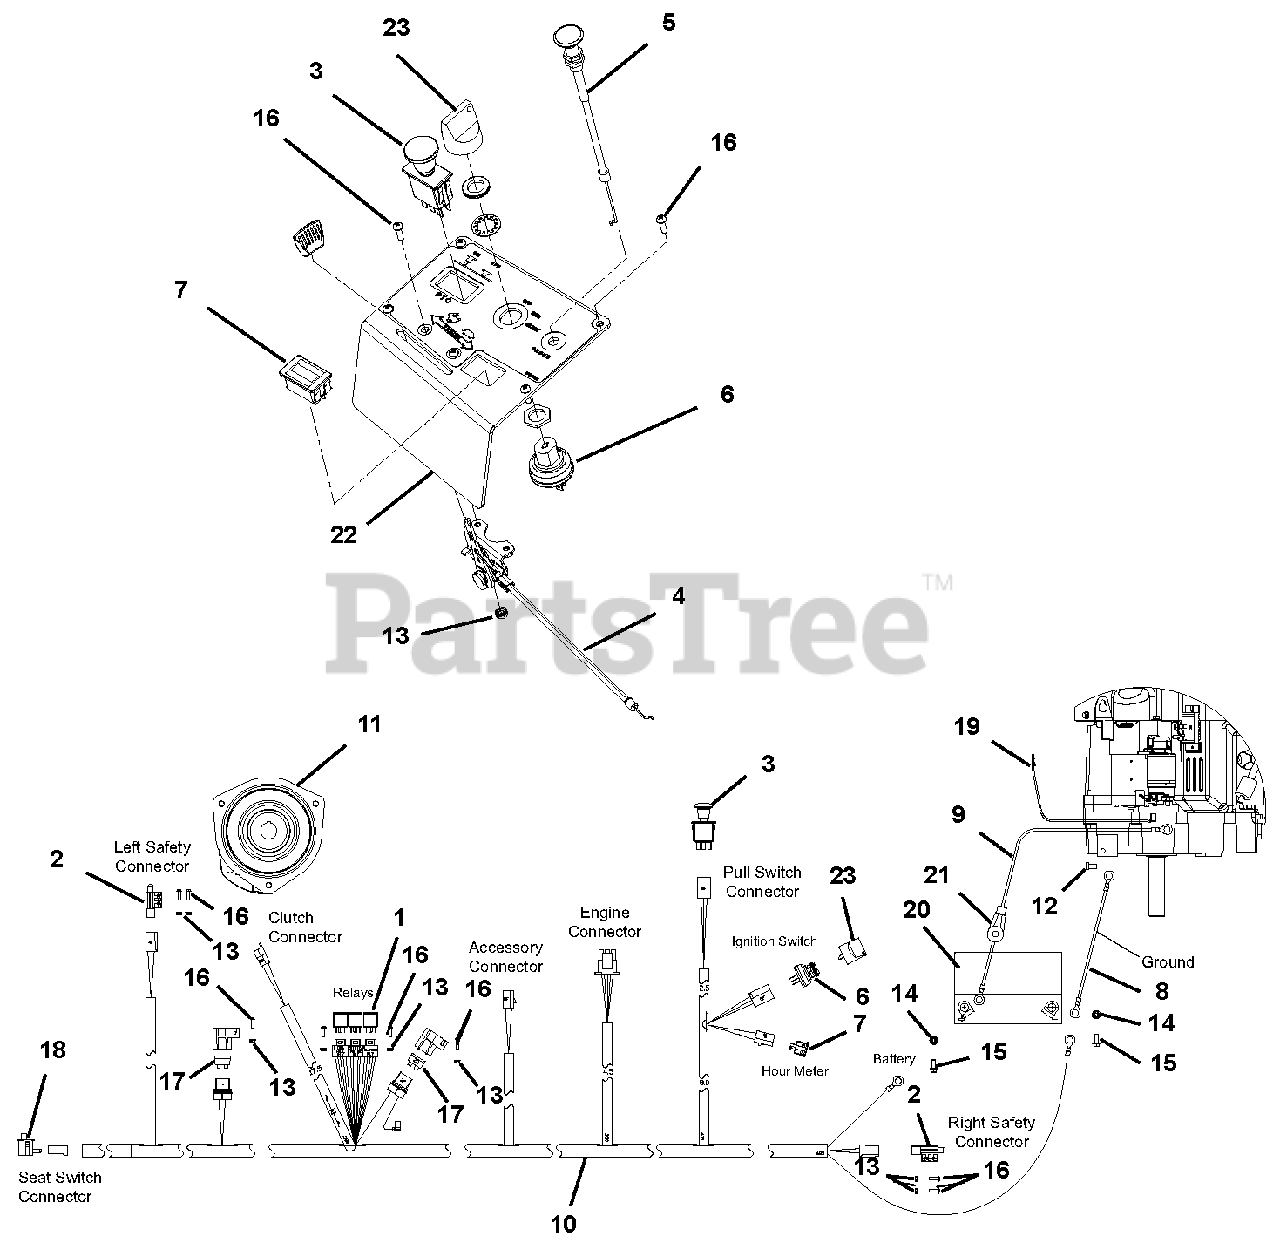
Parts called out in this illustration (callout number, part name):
1	Relay, ISO Mini Electric
2	Switch, Plunger
3	Switch, Clutch (Serials 101 – 2499)
3	Switch, Clutch (Serials 2500 and up)
4	Cable, Pro-Control Throttle (Serials 101 – 2499)
4	Cable, Pro-Control Throttle (Serials 2500 and up)
5	Cable, Pro-Control Choke (Serials 101 – 2499)
5	Cable, Pro-Control Choke (Serials 2500 and up)
6	Switch, Ignition (Includes item 23)
7	Meter, Hour-LCD ALT (Serials 101 – 2499)
7	Meter, Hour-LCD ALT (Serials 2500 and up)
8	Cable, Battery - 25" Ground
9	Cable, Battery - 42" Positive
10	Harness, Wiring
11	Clutch, Electric - OGURA, GT3
12	Bolt, M8 x 1.25 x14 Hex 8.8
13	Locknut, 10-24 KEPS (Serials 101 – 2499)
13	Locknut, 10-24 KEPS (Serials 2500 and up)
14	Nut, Locking, Flange .25-20
15	Bolt, 1/4-20 x .625 WSH
16	Screw, Hex, Flange .25-20 x .625
16	Screw, Machine 10-24 x .38 HWH Stainless (Serials 2500 and up)
16	Screw, Machine 10-24 x .50 HWH (Serials 2500 and up)
17	Fuse, 20 AMP Blade S/O
18	Seat Switch
19	Lead, Starter Solenoid
20	Battery, 12V
21	Battery Terminal Boot, Red
22	Control Panel (Serials 101 – 2499)
22	Control Panel (Serials 2500 and up)
23	Key, w/Shield
